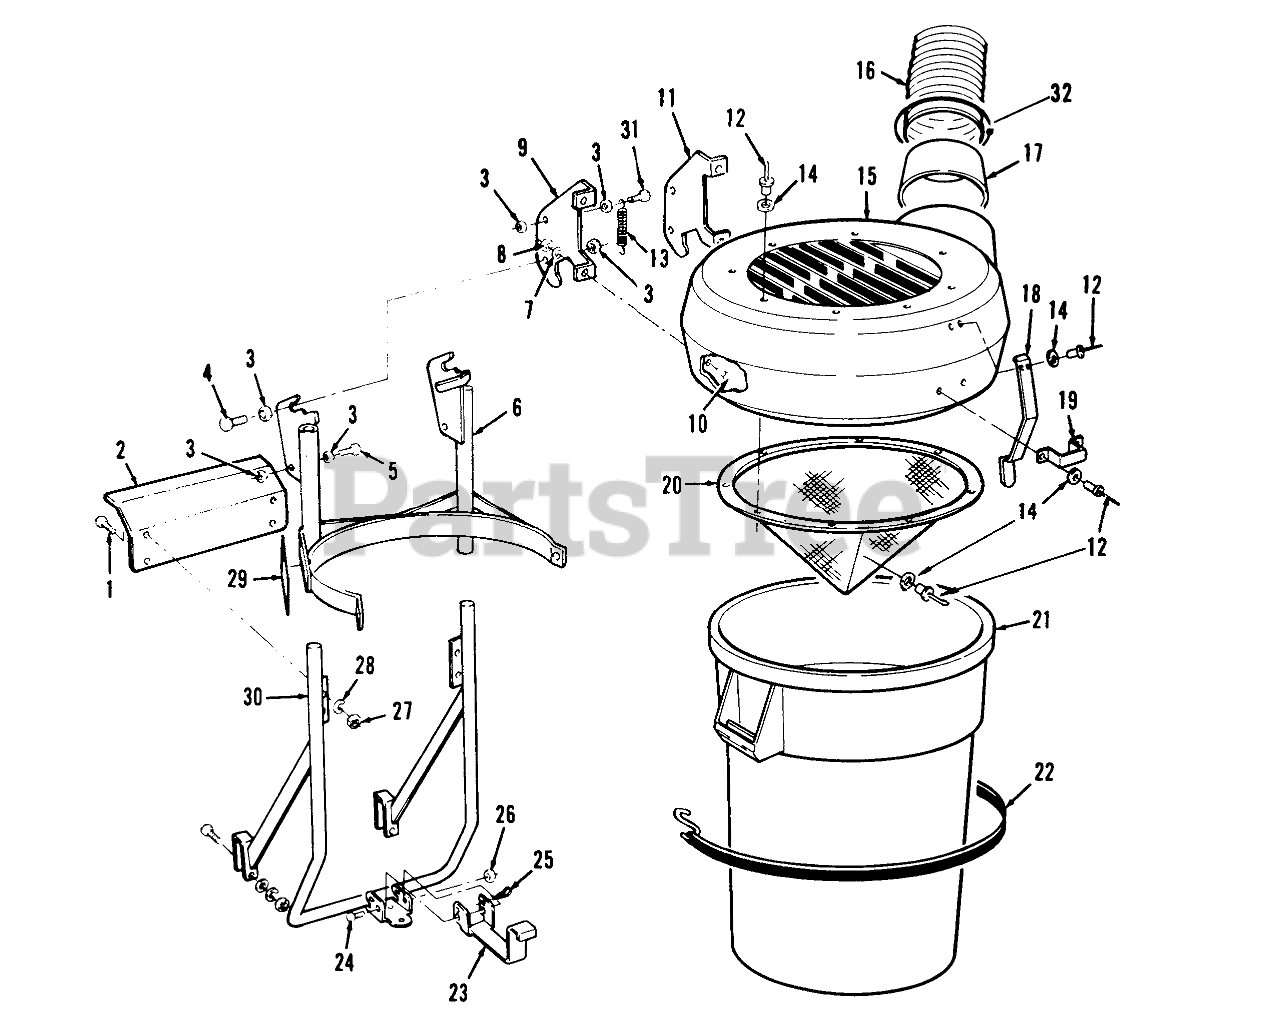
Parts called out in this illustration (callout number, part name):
1	SCREW-HH
2	SHIELD-HEAT B
3	NUT-HEX
4	SCREW-HH
5	SCREW-HH
6	Support-Canister
7	WASHER-PLAIN
8	NUT-LOCK, NI
9	LH TOP BRACKET B
10	SCREW-HH
11	RH TOP BRACKET B
12	RIVET-POP
13	SPRING-EXTENSION
14	Washer
15	TOP-CANISTER
16	HOSE 6" X 48"
17	SEAL ASSEMBLY NP
18	LATCH-BAGGER TOP B
19	BRACKET B
20	SCREEN-BAGGER TOP
21	CANISTER
22	STRAP B
23	BRACKET-SUPT B
24	Screw-Cap Hex. Hd.
25	Hairpin
26	NUT-LOCK, NI
27	NUT-LOCK, NI
28	WASHER-PLAIN
29	DECAL-DANGER
30	MOUNT-BAGGER W.A. B
31	SCREW-HH
